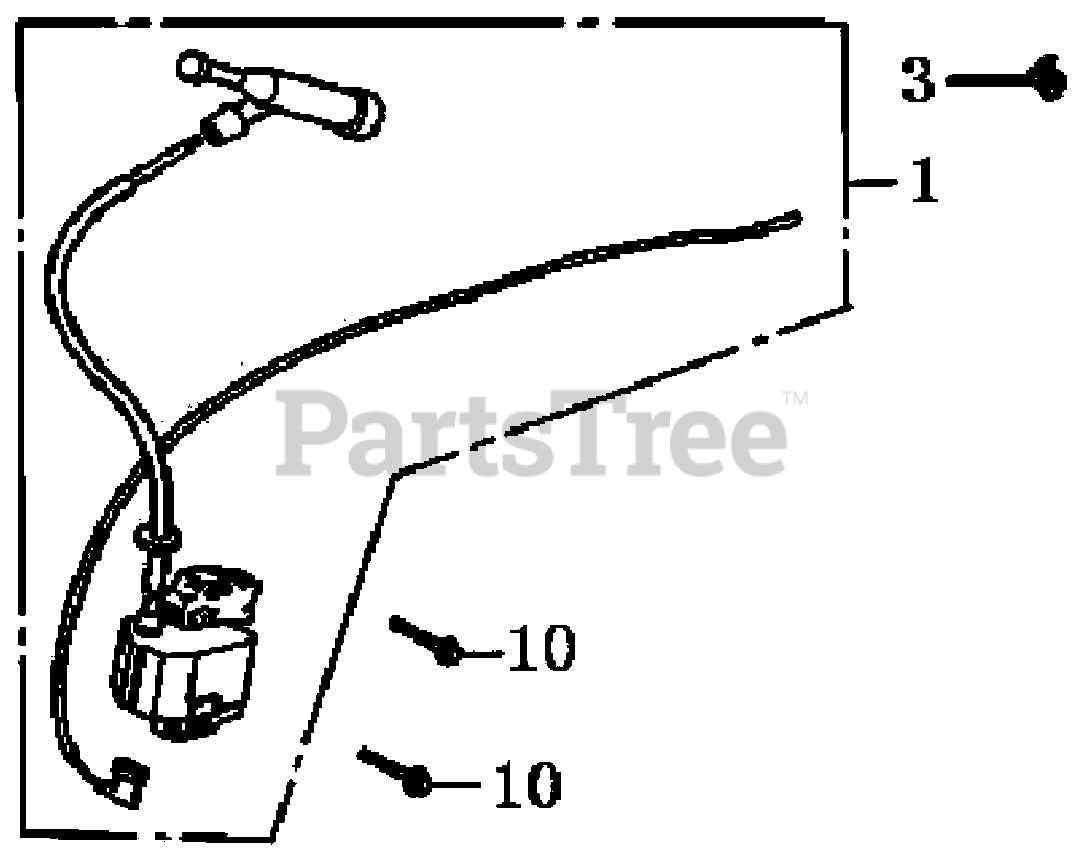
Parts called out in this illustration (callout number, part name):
1	COIL ASSY., IGNITION
3	HOLDER, STOP SWITCH
10	BOLT, FLANGE
